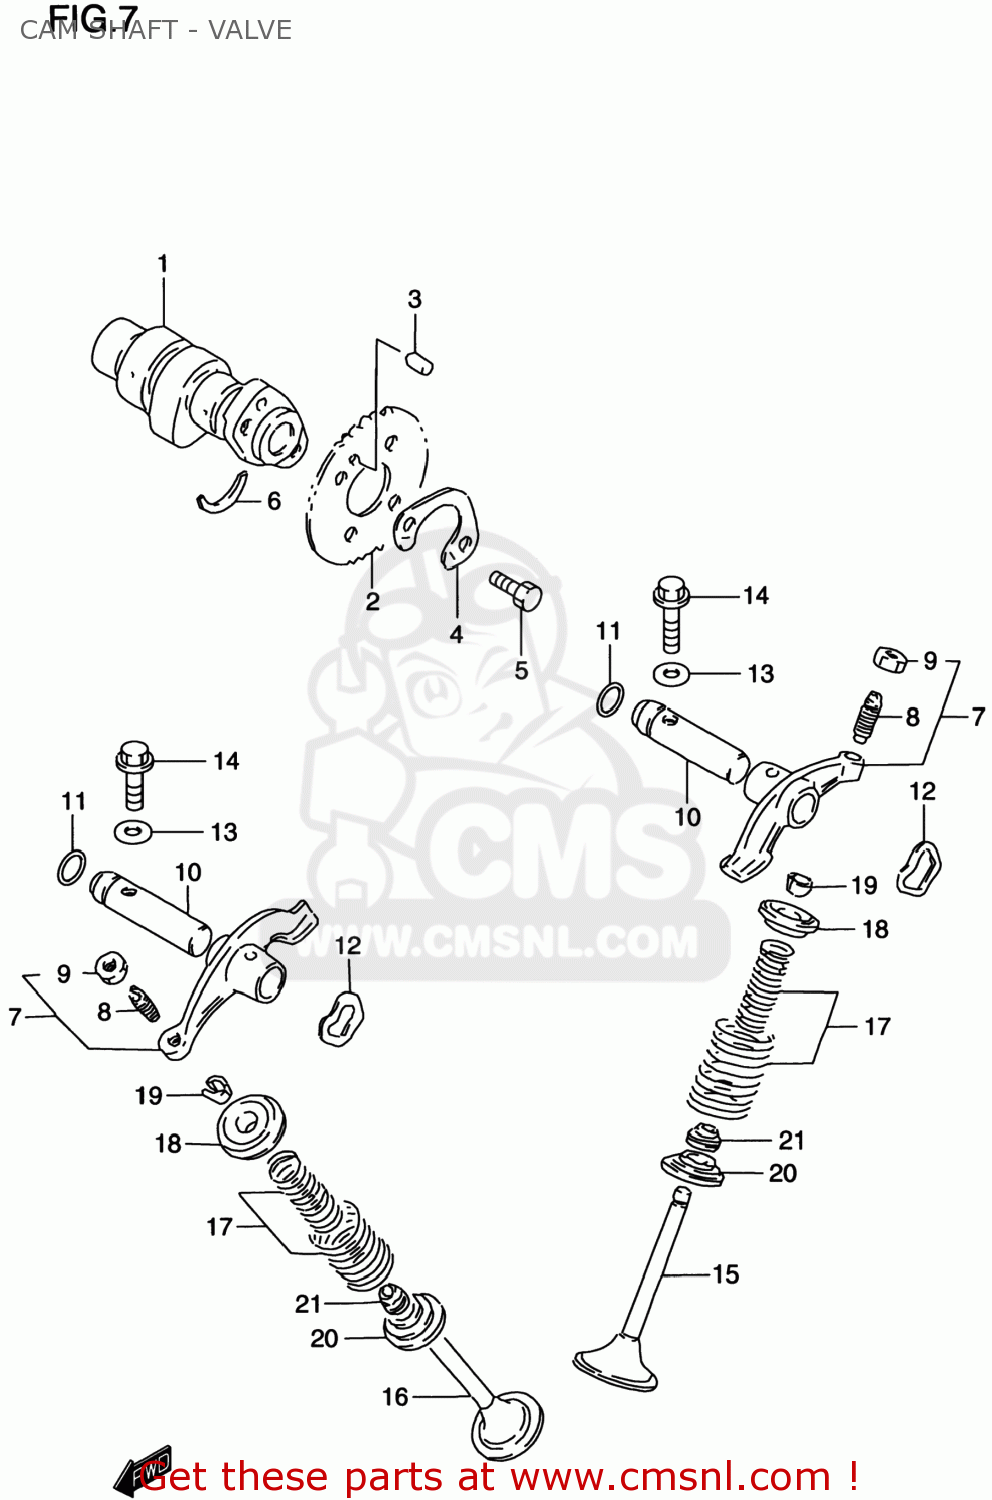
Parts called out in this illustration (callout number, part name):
1	CAMSHAFT
2	SPROCKET,CAMSHAFT
3	PIN(5X8)
4	WASHER,SPROCKET
5	BOLT(6X10.5)
6	C RING
7	ARM ASSY,VALVE ROCKER
8	SCREW,TAPPET ADJUSTING
9	NUT,ADJUSTING SCREW
10	SHAFT,VALVE ROCKET
11	O RING(D:1.9,ID:8.6)
12	WASHER
13	GASKET(5.8X13X1.2) (NAS)
14	BOLT
15	VALVE,INTAKE
16	VALVE,EXHAUST
17	SPRING SET,VALVE
18	RETAINER,VALVE SPRING
19	COTTER,VALVE
20	SEAT,VALVE SPRING
21	SEAL,OIL(5.5X11X8.2)
